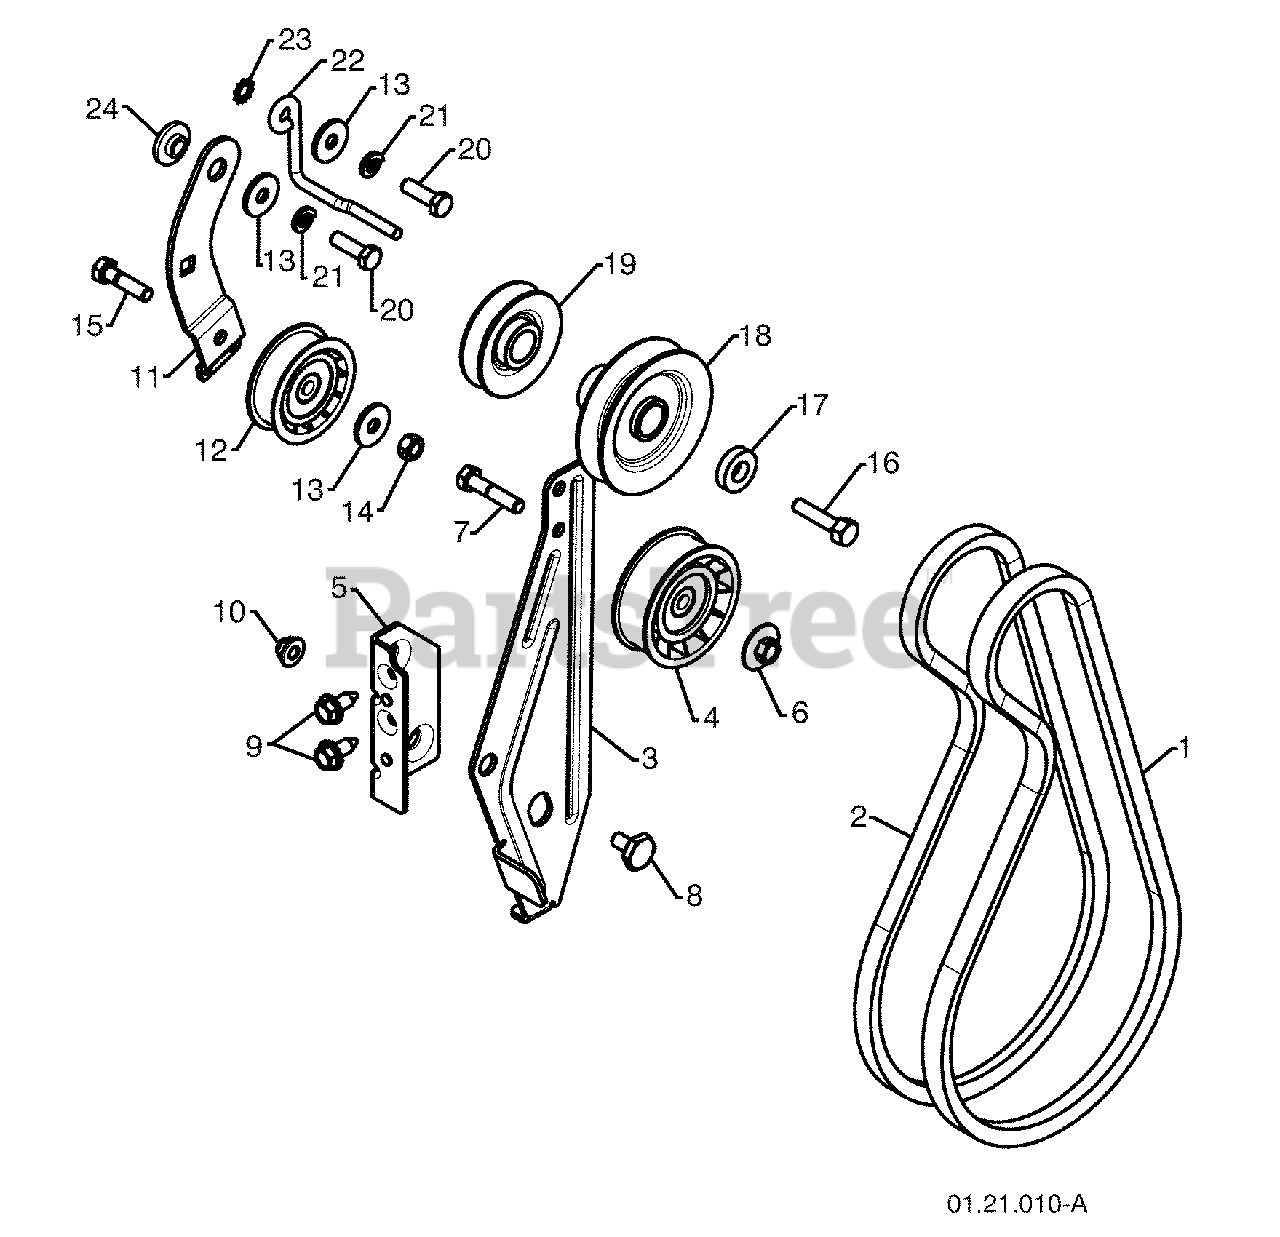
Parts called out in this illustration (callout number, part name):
1	IMPELLER BELT
2	TRACTION BELT
3	IDLER ARM BRACKET
4	IDLER PULLEY
5	IDLER BRACKET
6	NUT 5/16-18
7	SCREW 5/16-18 X 1.50
8	SHOULDER BOLT 5/16-18 X .50
9	SCREW 5/16-18 X .625
10	NUT 5/16-18 NYLOCK
11	TRACTION IDLER BRACKET
12	TRACTION PULLEY
14	NUT 5/16-18
15	SCREW 5/16-18 X 1.25
16	SCREW 3/8-24 X 1.375
18	PULLEY ENG IMPELLER
19	PULLEY ENG TRACTION
20	SCREW 5/16-24 X 1.00
21	LOCKWASHER 5/16
22	BELT GUIDE
23	LOCKWASHER 5/16
24	IDLER BUSHING
